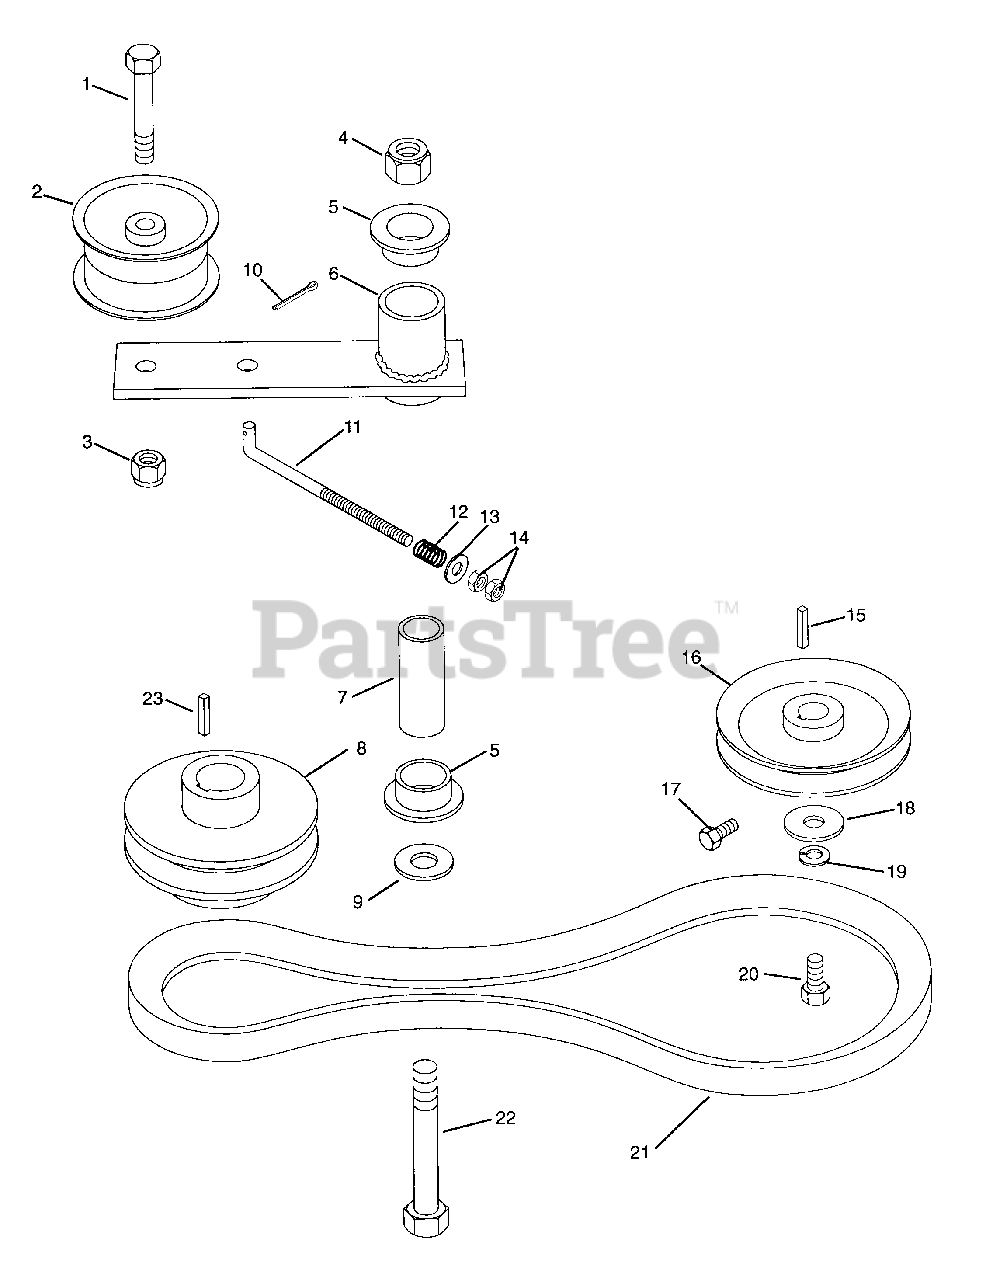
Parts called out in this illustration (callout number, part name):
1	Bolt-Hex .38-16 x 1.75 Grade 5
2	Idler-Pully Flat 3.25 x .625
3	Nut-Locking-Center .375-16
4	Nut-Locking-Center .50-13
5	Bushing-Flange .762 x 1.0 x .580 x 1.48
6	Weldment-Ground Drive Idler
7	Bushing-Steel .560 x .745 x 2.04
8	Pulley-V 4.00 x 1.125 w/Key
9	Washer-Flat-Steel .531 x 1.062 x .095
10	Pin-Center .09 x .75
11	Rod-Idler 11.0 Large
12	Spring-Compression .125 x .78 x 1.00
13	Washer-Flat-Steel .406 x .812 x .065
14	Nut-Locking-Nylon w/Insert .375 x 24
15	Key-Straight 5mm x 25mm x 5mm
16	Sheave 4.0 x .199
17	Bolt-Hex .25 x 20 x 1.25 Grade 5
18	Washer-Flat-Steel .25 x 1.0 x .048
19	Washer-Locking .25
20	Bolt-Hex M6 x 1.0 12
21	V-Belt A-RMA 28.22 x 33/64
22	Bolt-Hex .50 - 13 x 3.00 Grade 5
23	Key-Square .25 x 1.00 x .25
